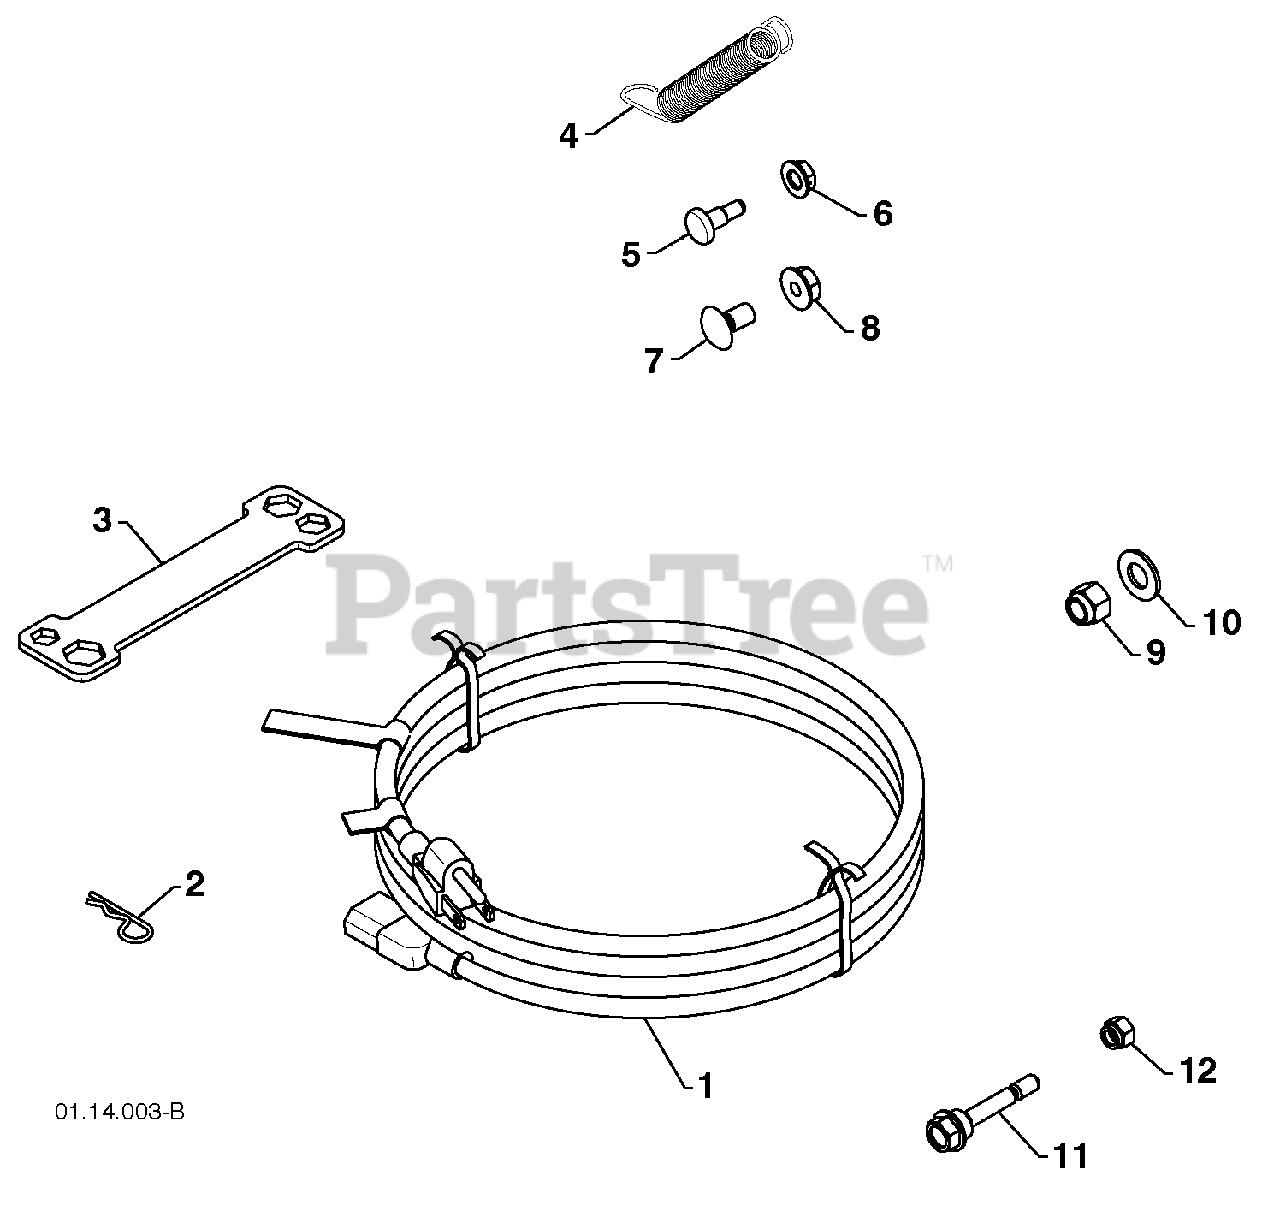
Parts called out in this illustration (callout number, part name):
1	POWER CORD
2	RETAINER PIN
3	WRENCH
4	REMOTE SPRING
5	SHOULDER BOLT 1/4-20
6	LOCKNUT 1/4-20
7	CARRIAGE BOLT 5/16-18 X 5/8
8	LOCKNUT 5/16-18
9	LOCKNUT 3/8-16
10	WASHER 3/8
11	SHEAR BOLT 1/4-20 X 1-13/16
12	LOCKNUT 1/4-20
